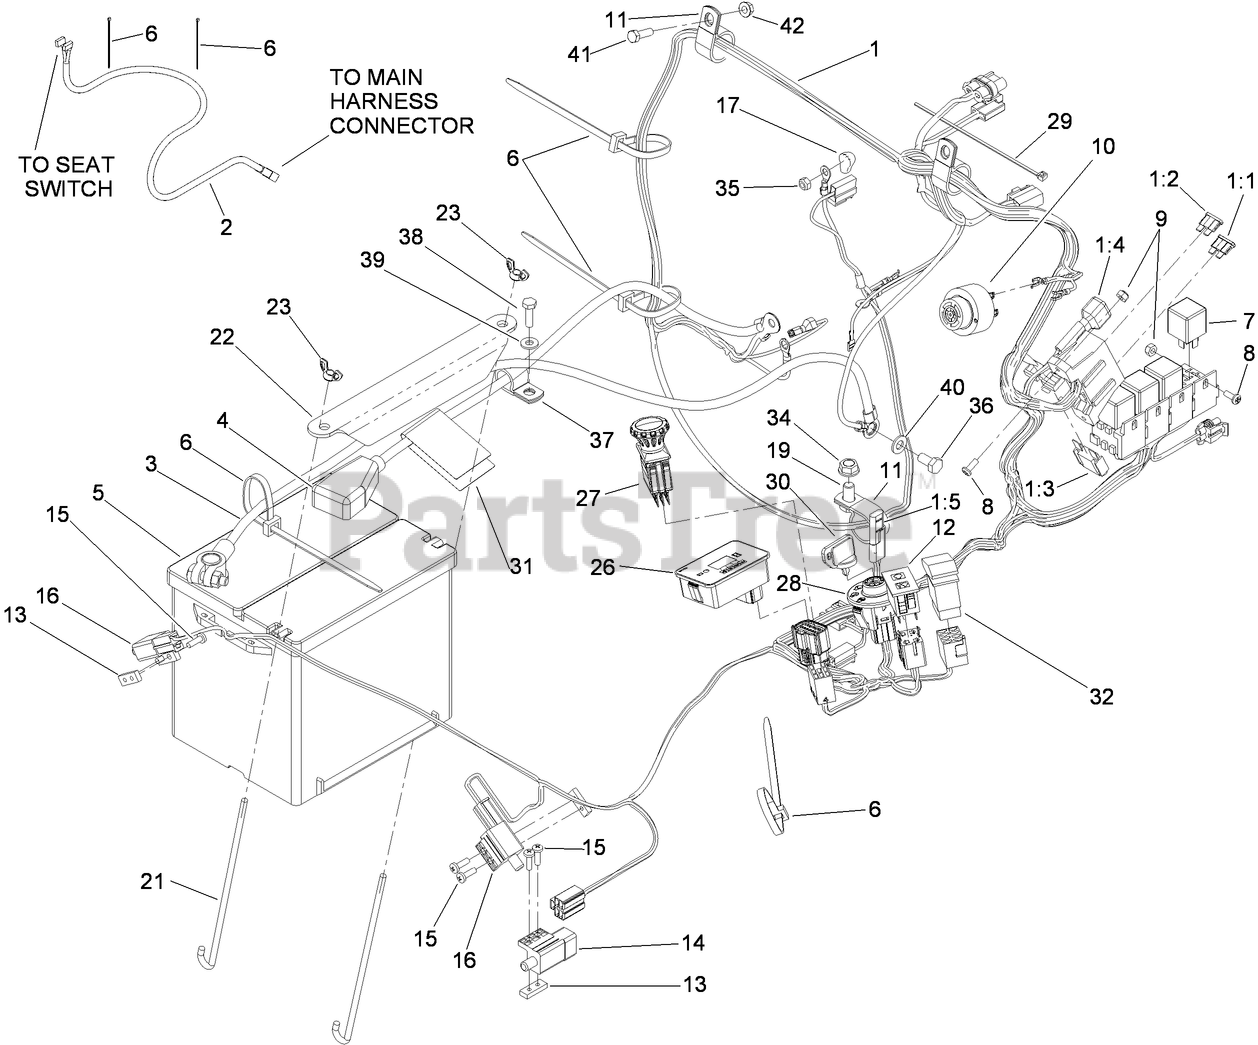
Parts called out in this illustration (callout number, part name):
1	HARNESS-WIRE
1:1	FUSE-BLADE, 10 AMP
1:2	FUSE-BLADE, 30 AMP
1:3	FUSE-BLADE, 50 AMP
1:5	CAP-PLUG
2	HARNESS-WIRING, SEAT
3	CABLE-BATTERY, NEGATIVE
4	CABLE-BATTERY, POSITIVE
5	BATTERY-DRY
6	TIE-PLASTIC
9	NUT-LOCK, NI
10	ALARM-TONE, DUAL
11	CLIP-LOOM
12	LAMP-WARNING
13	PLATE-TAPPED
14	SWITCH
15	SCREW-PPH
16	SWITCH-OPEN, NORMALLY
17	CAP-INSULATOR, RED
19	SCREW-HH
21	Bolt-Holddown
22	HOLDDOWN-BATTERY
23	WINGNUT
26	HOUR METER ASM
27	SWITCH-PTO, 10 AMP
28	SWITCH-IGNITION
29	TIE-CABLE
30	KEY-IGNITION
31	DECAL-INSTRUCTIONS, CHARGING
32	SWITCH-ROCKER
34	NUT-HHF, WHIZ
35	NUT-LOCK
36	SCREW-HH
37	CLIP-LOOM
38	SCREW-HH
39	WASHER-FLAT
40	WASHER-PLAIN
41	SCREW-HH
42	NUT-HF
